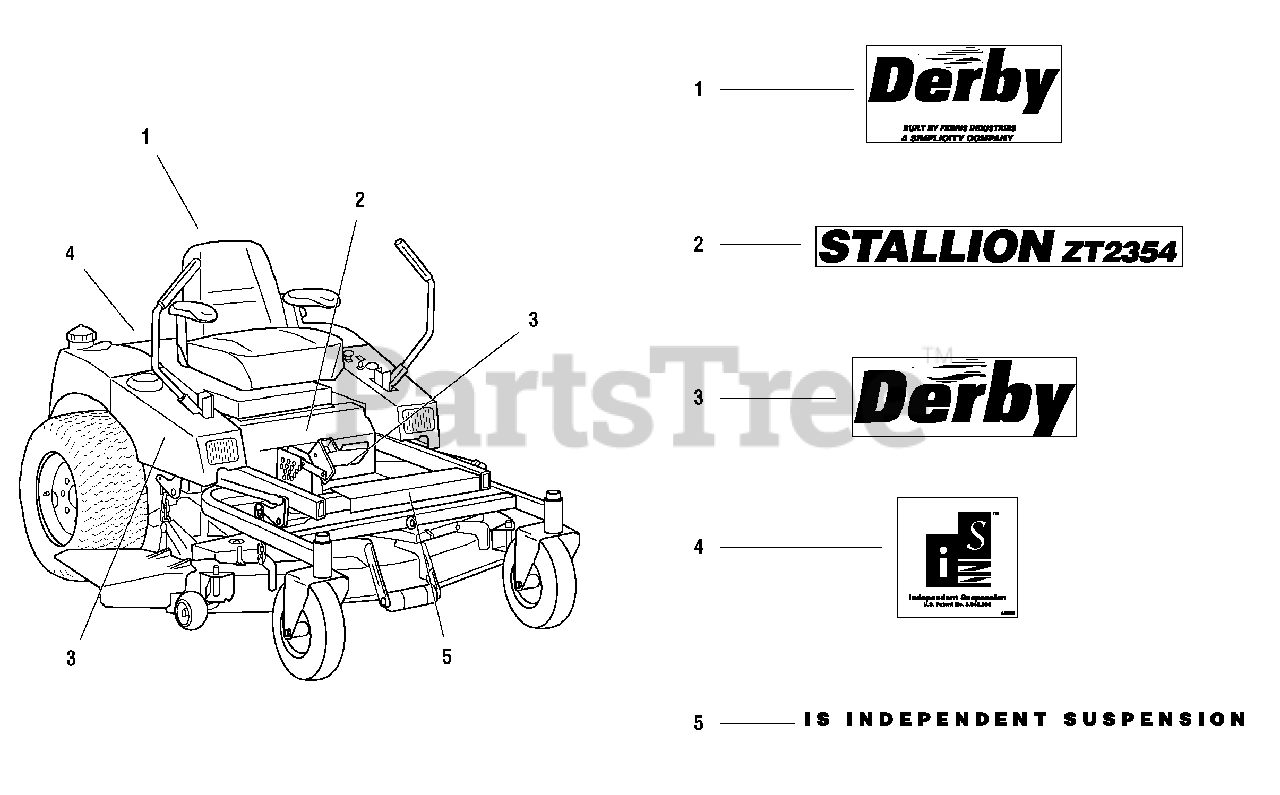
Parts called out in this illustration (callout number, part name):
1	DECAL, Derby Built By Ferris (located on back of seat)
2	DECAL, Stallion ZT2354
3	DECAL, Derby
4	DECAL, IS Logo (located on the fuel tank tire bar)
5	DECAL, IS Independent Suspension
